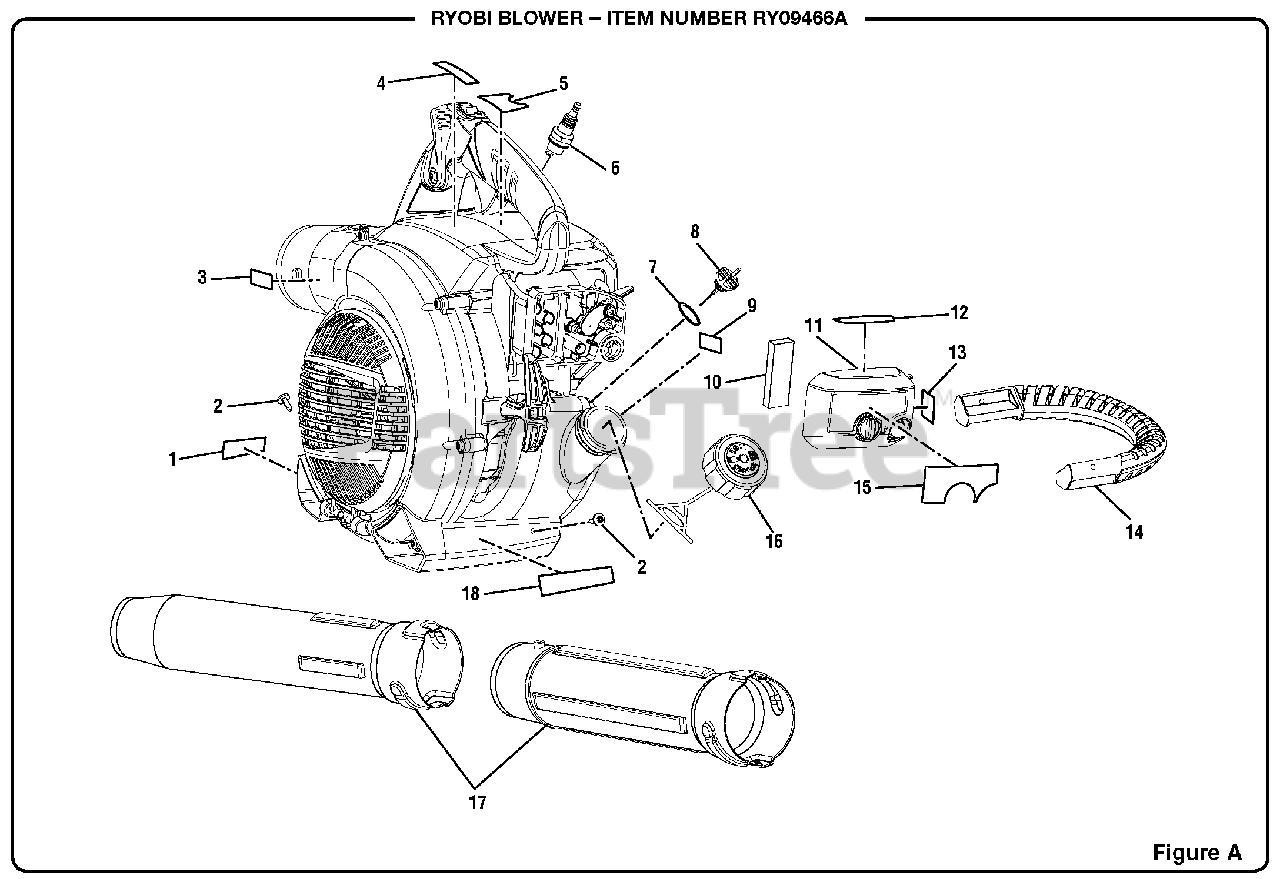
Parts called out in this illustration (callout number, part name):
1	Combustion Warning Label
2	Screw (#10-14 x 1/2 in., T25 Torx Truss Hd. T.F.)
3	Logo Label
4	Warning Label
5	Logo Label
6	Spark Plug (Champion RY4C)
8	Oil Fill Cap w/Dipstick
9	Add Oil Label
11	Air Filter Cover
12	Stop Label
13	Run/Start Label
15	Starting Label
16	Fuel Cap Assembly
17	Sweeper Nozzle & Upper Blower Tube Assembly
18	No Mix Label
